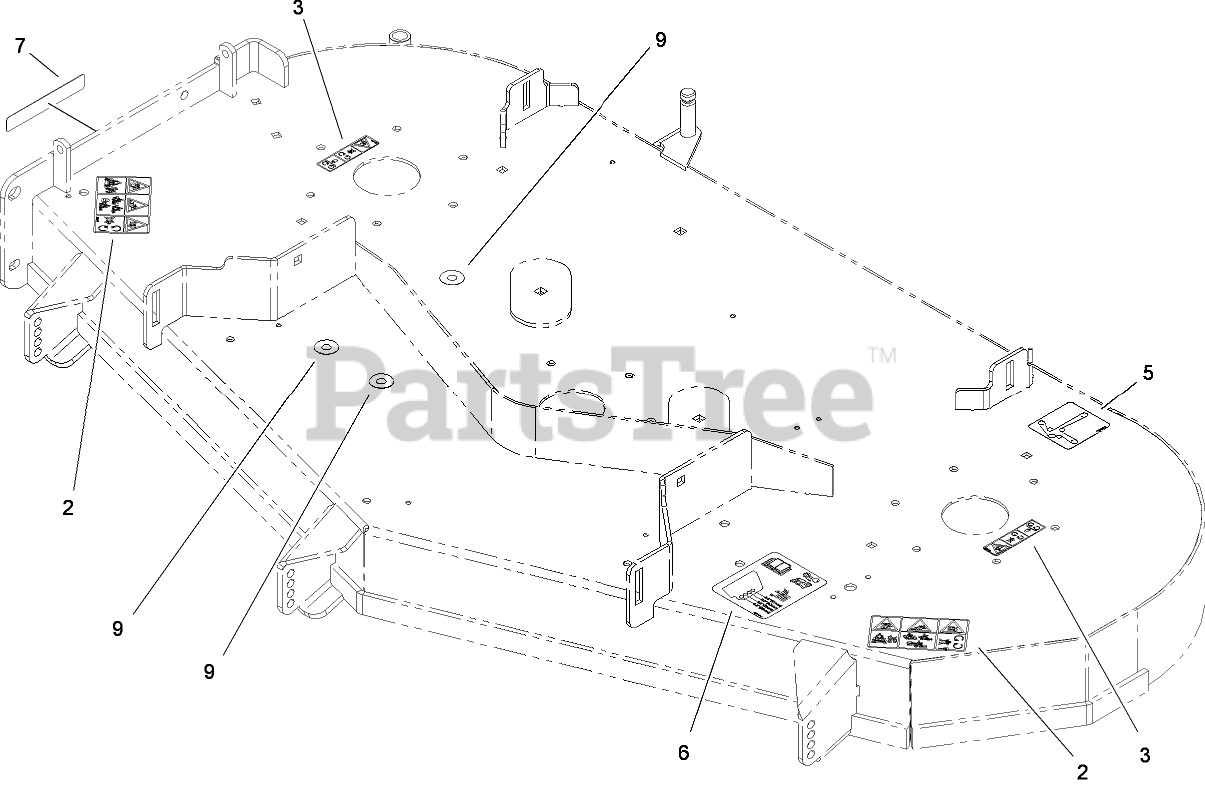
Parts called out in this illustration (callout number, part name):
2	DECAL-DANGER
3	DECAL-WARNING, BELT SHIELD
5	DECAL-BELT ROUTING
6	DECAL-ROLLER, ANTI-SCALP
7	DECAL-DANGER
9	DECAL-COVER, HOLE
